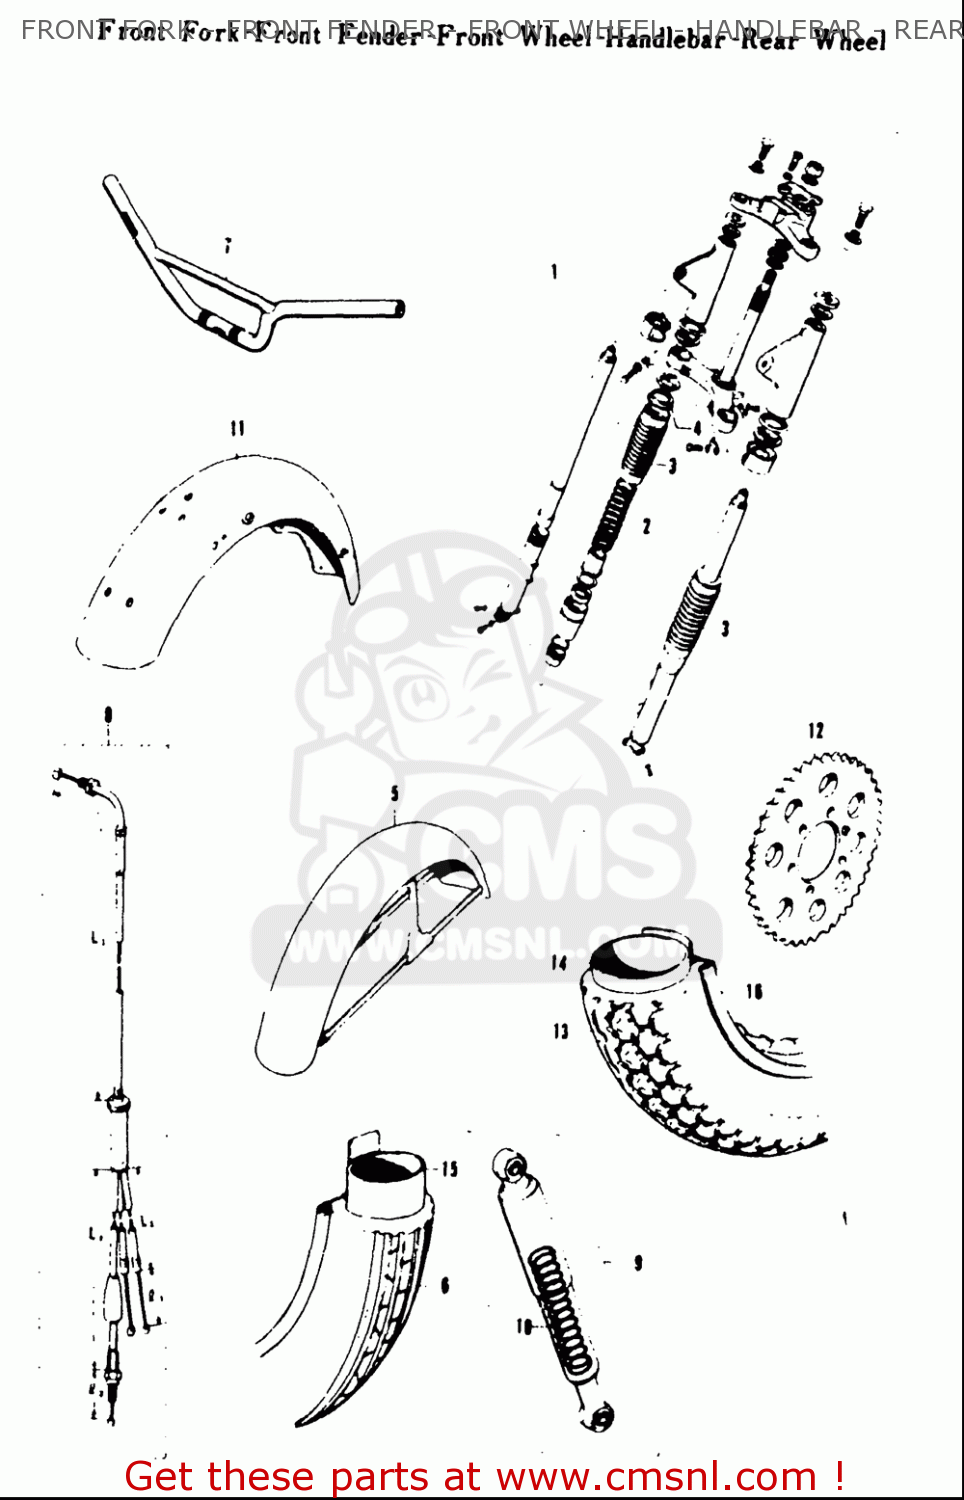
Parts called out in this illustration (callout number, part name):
3	BOOT,SPRING COVER
16	RIM,RR WHEEL
17	SCREW
